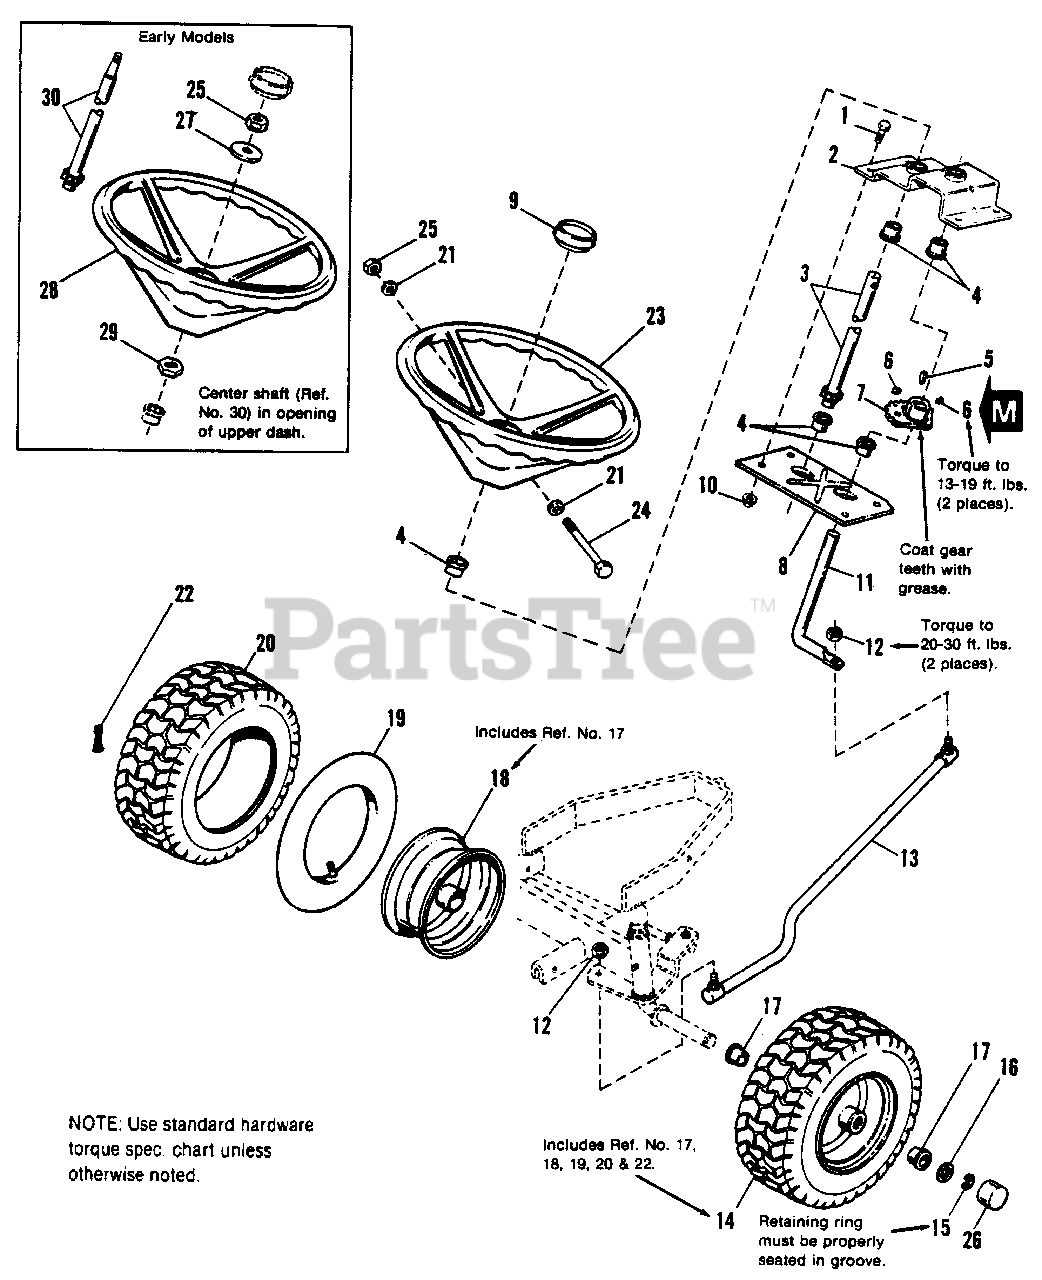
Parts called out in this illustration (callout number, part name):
1	CAPSCREW, Hex Hd., 5/16-18 x 3/4
2	PLATE, Steering
3	SHAFT ASSY., Steering
6	SETSCREW, 5/16-18 x 1/2
7	GEAR, Steering
8	PLATE, Base, Steering
9	CAP, Steering Wheel
10	LOCKNUT, Hex, Flange, 5/16-18
11	ROD, Steering
12	NUT, Special, 3/8-24
14	WHEEL & TIRE ASSY.
18	WHEEL ASSY.
19	TUBE, 4.10/3.50-6 (See Note Below)
20	TIRE, 15 x 6.00-6 (Carlisle)
20	TIRE, 15 x 6.00-6 (Goodyear)
21	WASHER, Plain
22	VALVE STEM & CAP
23	WHEEL, Steering
24	BOLT, Hex, 5/16-18 x 3-1/2
25	LOCKNUT, Hex, 5/16-18
26	CAP, Hub, Threaded
27	WASHER, Compression
28	WHEEL, Steering
29	WASHER, Hex
30	SHAFT ASSY., Steering
